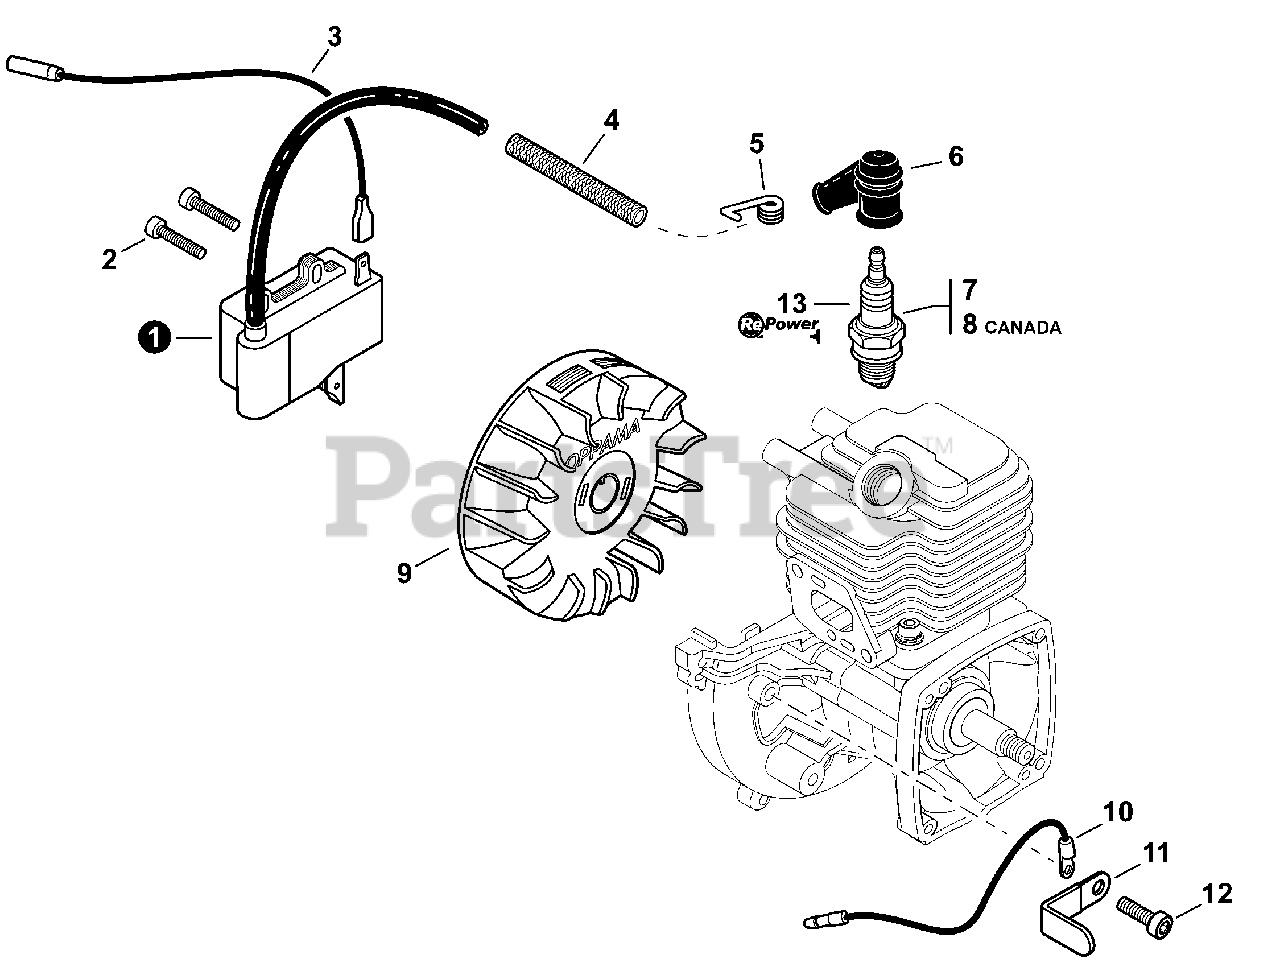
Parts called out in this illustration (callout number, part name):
1	COIL, IGNITION
2	BOLT, TORX 4x20
3	LEAD - IGNITION L= 210
4	TUBE, INSULATOR 8 L= 65
5	TERMINAL, SPARK PLUG
6	CAP, SPARK PLUG
7	SPARK PLUG - BPM8Y
8	SPARK PLUG - BPMR8Y
9	FLYWHEEL
10	LEAD - GROUND L= 115
12	BOLT, TORX 5x10
13	TUNE-UP KIT - REPOWER
